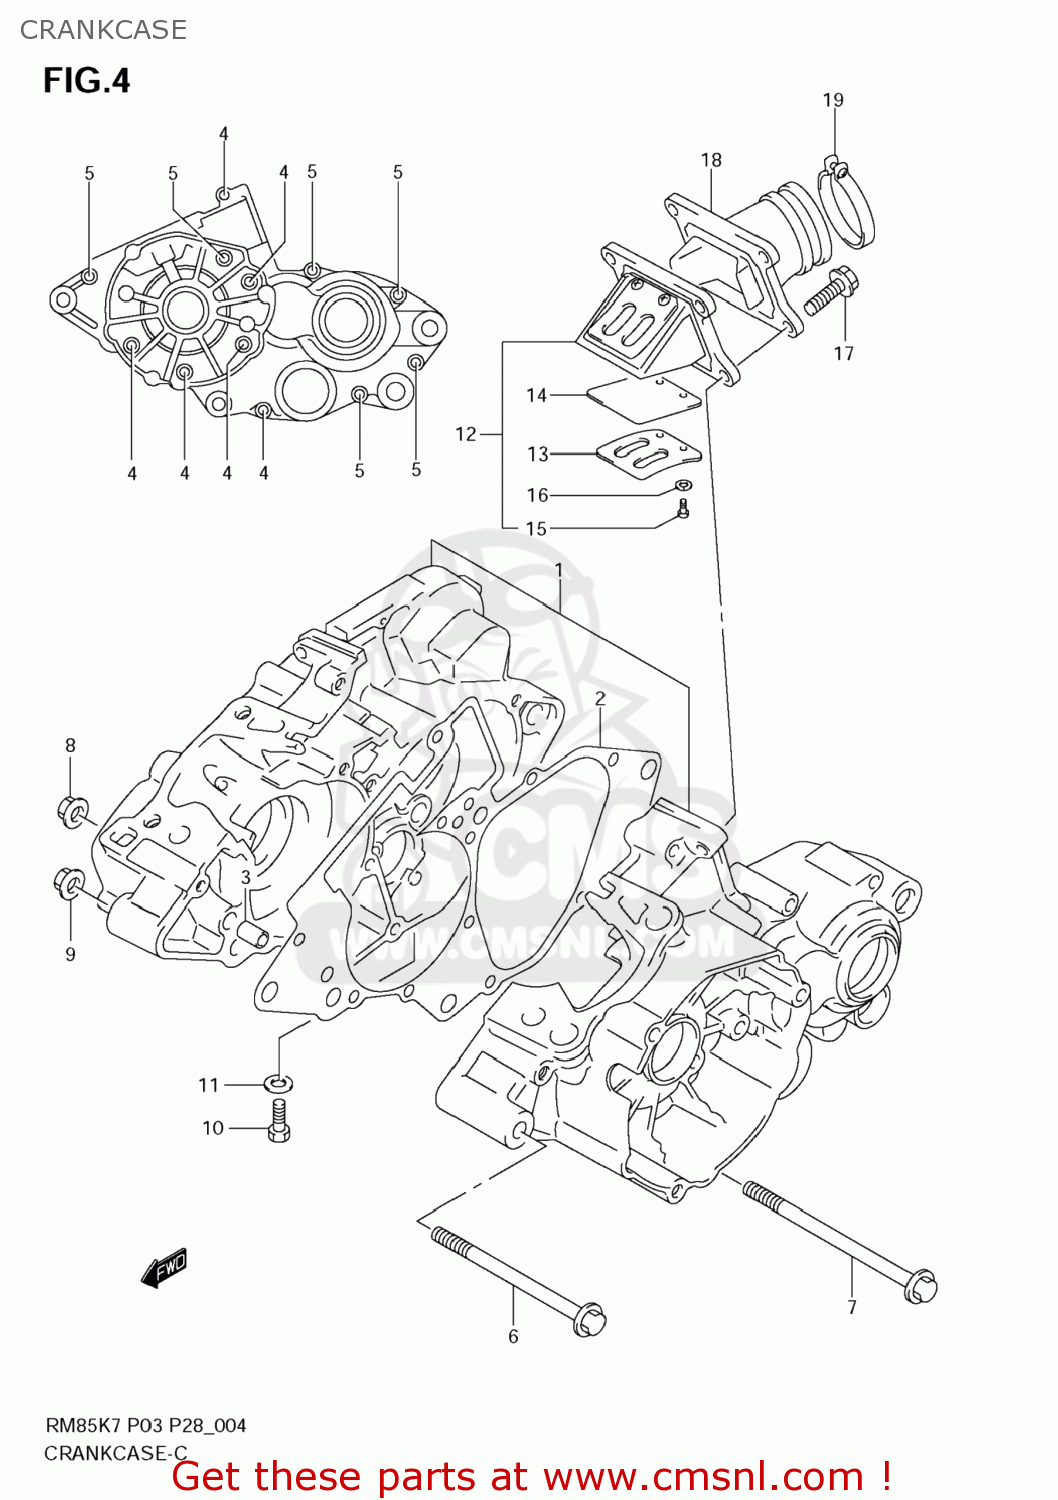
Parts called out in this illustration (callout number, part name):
1	CRANKCASE SET
2	GASKET,CRANKCASE (NAS)
3	PIN
4	BOLT
5	BOLT(6X50)
6	BOLT(10X95)
7	BOLT(8X102)
8	NUT
9	NUT
10	BOLT
11	GASKET(8.2X14X1) (NAS)
12	VALVE ASSY,REED
13	STOPPER,REED VALVE
14	VALVE,REED
15	SCREW
16	WASHER,LOCK
17	BOLT,6X20
18	PIPE,INTAKE
19	CLAMP
